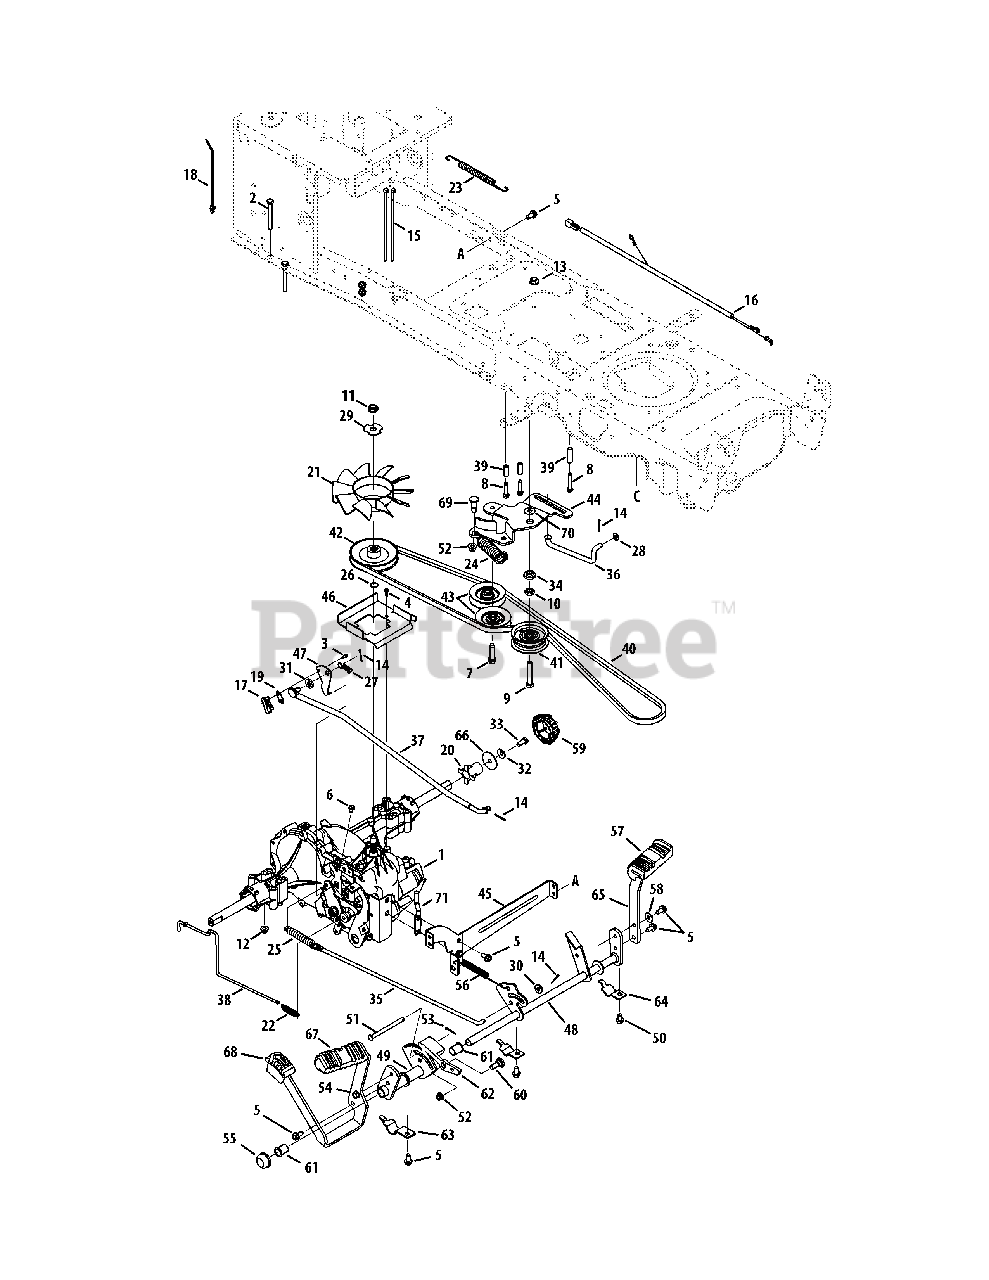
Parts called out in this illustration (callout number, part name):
1	Transmission
2	Hex Screw, 5/16-18, 2.75, Gr5, Std
3	Screw, #8-18, 0.500,
4	Screw, #10-16, 0.500
5	Screw, Self-tapping, 5/16-18, .750
6	Screw, Self-tapping, 1/4-20, 0.375
7	Screw, Self-tapping, 3/8-16, 1.500
8	Screw, Self-tapping, 1/4-20, 1.625
9	Hex Screw, 3/8-16, 2.25, Gr5
10	Nut, Jam, 7/16-20, Gr2
11	Nut, Jam Lock, 1/2-20, Gr5, Nylon
12	Nut, Flange Lock, 5/16-18, Nylon
13	Nut, Flange Lock, 3/8-16
14	Pin, Cotter, 3/32, 1.0
15	Cable, Tie, 3/16 x .05 x 7.4
16	Jumper Harness, Ground & Reverse
17	Switch, Spring, Short
18	Tie, Cable, Push Mount 7.5
19	Plate, Insulator Nut
20	Sleeve, .765 Id x 1.500
21	Fan, Hydro
22	Spring, Extension, .48 Od x 2.03
23	Spring, Extension, .500 Dia x 12.6
24	Spring, Extension, 1.00 Dia x 4.75
25	Spring, Extension, .59 Od x 4.00
26	Ring, Wire
27	Spring, Extension, .375 Od x 1.44
28	Washer, Flat, .330 x .630 x .0635
29	Washer, Lock, Transmission Hydro
30	Washer, Flat, .344 x .750 x .120
31	Washer, Flat, .407x.812x.135, Ht
32	Washer, Bell, .340 x .872 x .060
33	Hex Screw, 5/16-24, .750, Gr5, Lock
34	Spacer, Shoulder, 1.375 x .380 x .183
35	Rod, Brake, LT Hydro
36	Rod, Transmission, Bypass
37	Rod, Control, Hydro
38	Rod, Hydro Bypass
39	Spacer, .260 x .372 x 1.420
40	Belt, V-Type
41	Pulley, Idler, Flat 2.75 OD
42	Pulley, Input, 4.13 Dia
43	Pulley, Idler, V-Type x 3.06
44	Bracket, Idler, Center Double
45	Bracket, Mount, Hydro
46	Bracket, Support, Belt Disengage
47	Bracket, Actuator, Switch
48	Control Assembly, Brake
49	Bracket Assembly, Pedal, Hydro
50	Screw, Self-tapping, 5/16-18, 0.625,
51	Pin, Clevis, 5/16 x 3.985
52	Nut, Flange Lock, 3/8-16, Nylon
53	Pin, Cotter, Bow-Tie 72
54	Bracket, Pedal, Hydro
55	Cap, Push 5/8
56	Spring, Extension, .63 Dia x 4.95
57	Pad, Pedal, Brake
58	Washer, Bell, .340 x .872 x .060
59	Cap, Hub
60	Bolt, Shoulder, .500 x .270, 3/8-16
61	Bearing, Flange, .630 x .695 x .60
62	Latch, Cruise
63	Bracket, Support, Pedal Strap
64	Bracket, Support, Pedal Strap 5/8
65	Bracket, Pedal, Brake
66	Washer, Flat, .350 x 1.59 x .062
67	Pad, Pedal, Forward
68	Pad, Pedal, Reverse
69	Scr, Shldr, .50 x .685 3/8-16
70	Washer, Flat, .385 x 1.0 x .030
71	Belt Keeper Rod
